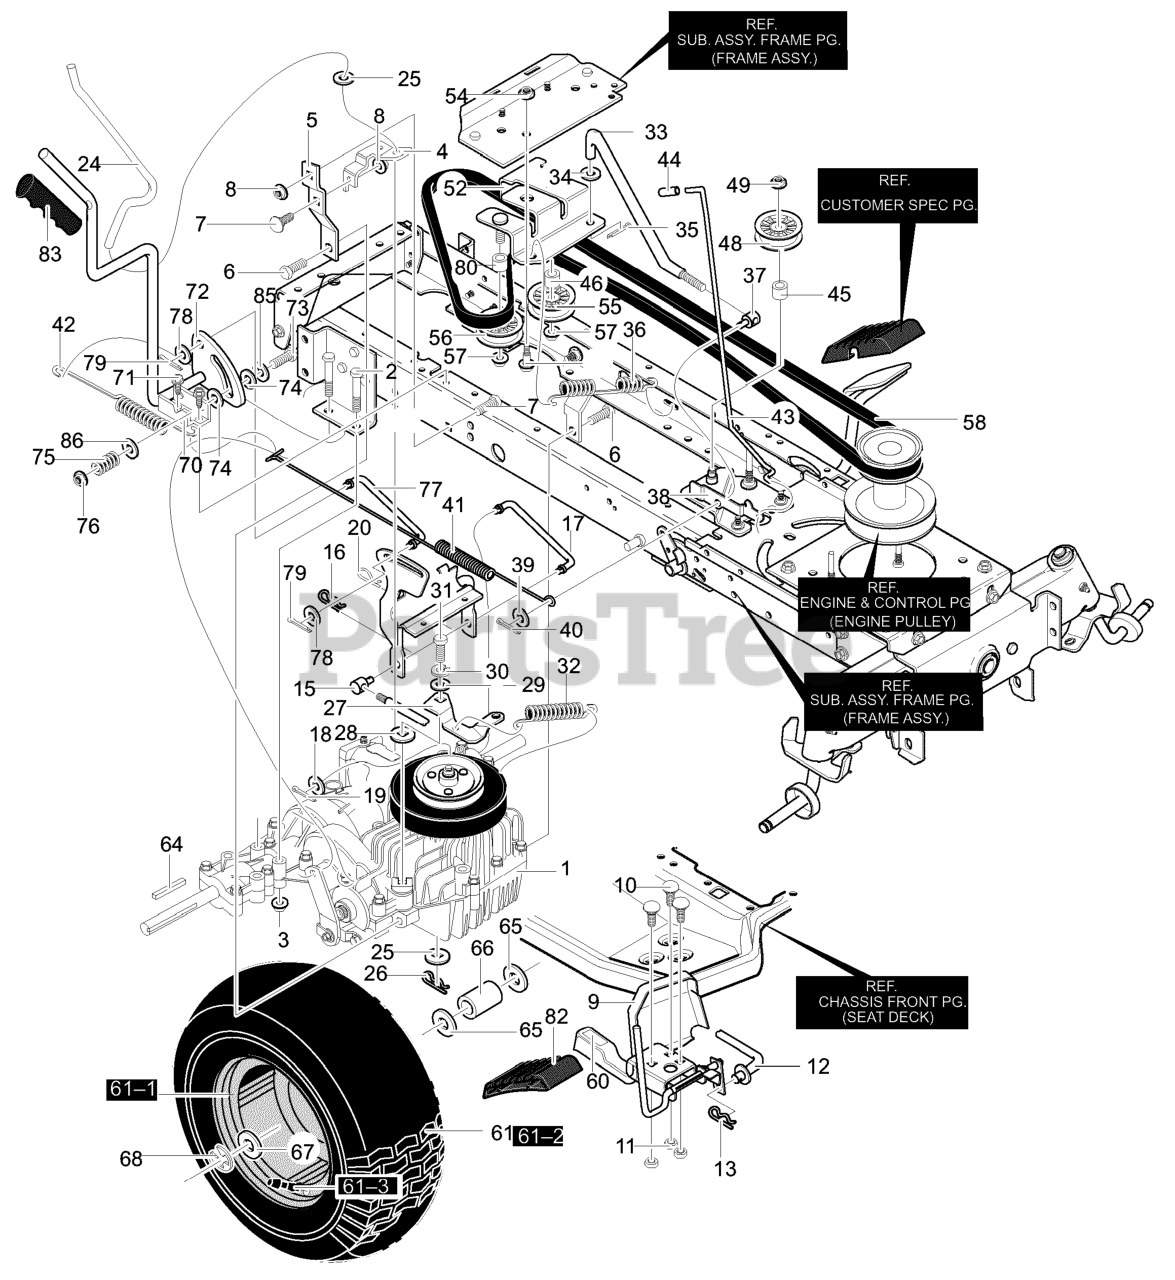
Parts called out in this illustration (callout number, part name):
1	Transaxle, VST205 **
2	Screw, 5/16-18 x 2.50
3	Nut, 5/16-18 Wdfllk
4	Bracket, Disconnect
5	Torque Strap
6	Screw, 5/16-18 x 0.75
7	Bolt, 5/16-18x.63
8	Nut, 5/16-18 Wdfllk
9	Pedal Assy., Hydro
10	Bolt, 5/16-18x.75
11	Nut, 5/16-18
12	Rod, Pedal Link
13	Hair Pin
15	Adjust Nut 1/2-13
16	Hair Pin
17	Rod Hydro Link
18	Flat washer
19	Cotter Pin
20	Hair Pin
24	Rod, Disconnect
25	Washer, Flat
26	Pin, Cotter
27	Arm Disconnect
29	Flat washer
30	Washer
31	Screw, 1/4-28x.75
32	Spring, Extension
33	Rod, Clutch
34	Flat washer
35	Cotter Pin
36	Spring, Clutch
37	Nut, Adjusting
38	Latch, Park Brake
39	Flat washer
40	Cotter Pin
41	Spring, Extension
42	Spring, Tension
43	Park Brake Rod
45	Spacer 1/2 to 17MM
46	Spacer 1/2 to 17MM
48	Pulley, Idler
49	Nut, 3/8-16
52	Asm., Bracket Idler
53	Bolt, 3/8-16
54	Nut, 3/8-16
55	Pulley, Idler
56	Pulley, Idler
57	Nut, 3/8-16
58	Belt, Motion Drive
60	Pad, Toe Sandpaper
61	Tire & Rim
61-1	Valve Stem
64	Key, Square
65	Flat washer
66	Spacer .87x1.78
67	Flat washer
68	Ring, E
70	Bracket, Mount Hand Ctrl
71	Screw, 5/16-18 x 0.75
72	Assy., Lever Hand Ctrl
73	Bolt, HHSH 5/16-18
74	Washer, Friction
75	Spring, Compression
76	Nut, 5/16-18
77	Link, Cruise Control
78	Flat washer
79	Cotter Pin
80	Spacer, 1/2 to 17MM
82	Pad, Speed Ctrl Pedal
85	Flat washer
86	Flat washer
